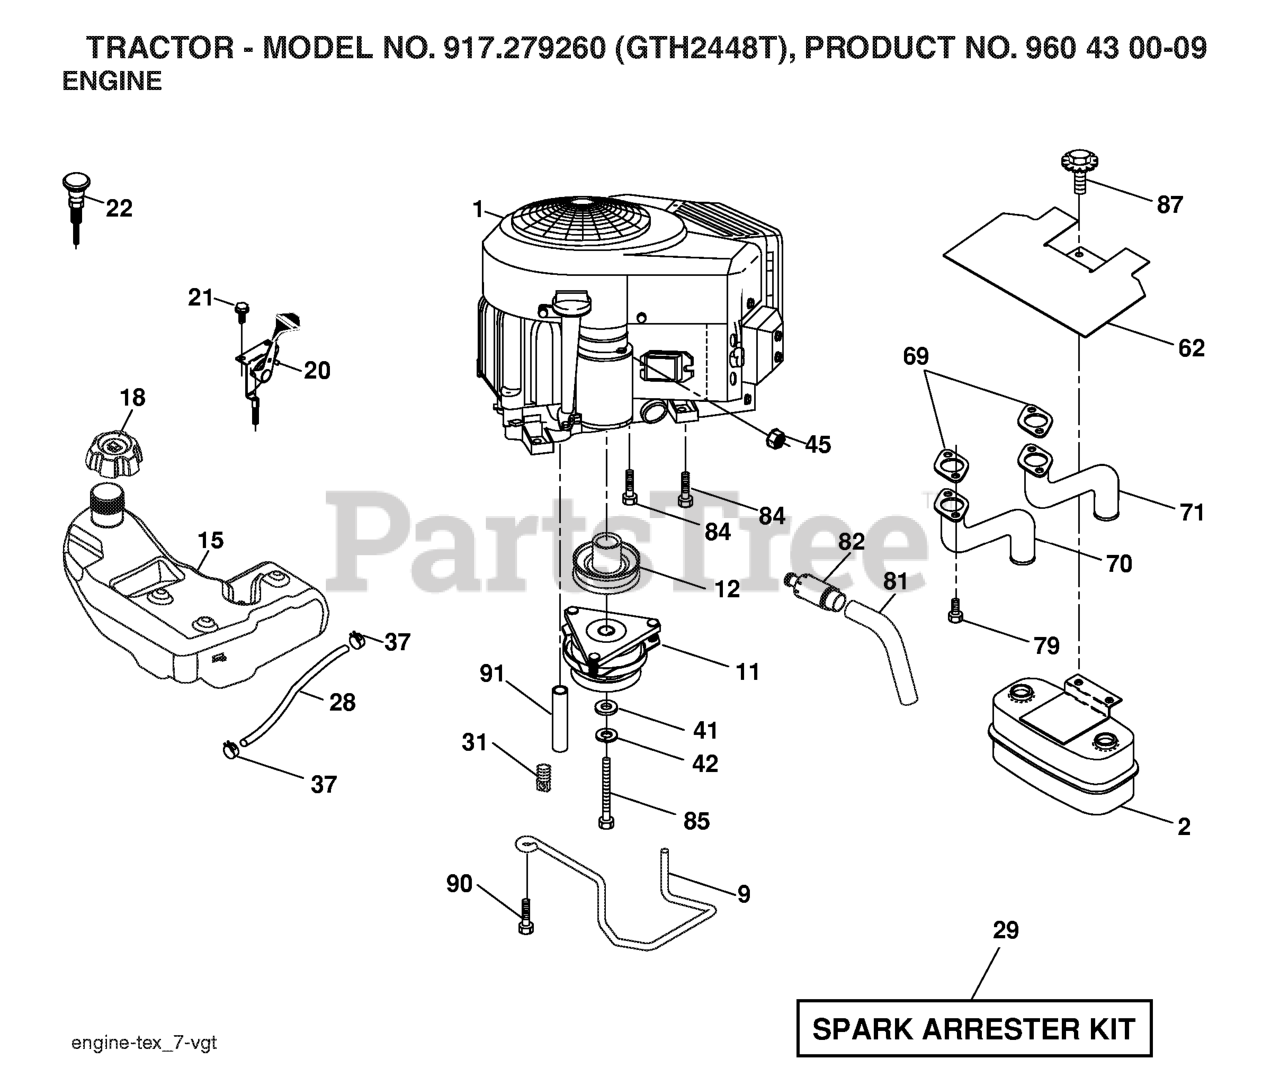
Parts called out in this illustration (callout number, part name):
2	MUFFLER.TWIN.CYL.LOW.TONE
9	KEEPER.BELT.ENGINE.3.25 (3 2)
11	CLUTCH MZ ZTR GT.48/54"1.125"
12	PULLEY.ASM.ENGINE.1-1/8X3-1/4
15	TANK.FUEL.4GAL
18	CAP.FUEL.TANK.3"GREY
20	THROTTLE CABLE
21	SCREW
22	CONTROL.CHOKE.ERGO.PUSH-IN.BLA
28	LINE.FUEL.64"REAR.EMIS
29	KIT.SPARK ARRESTOR 794945 B&S
37	HOSE CLAMP
42	LOCKWASHER
45	NUT
62	RP SHIELD HEAT MUFFLER
69	GASKET.MUFFLER
70	RP.EXHAUST.TUBE.LH.BS/TWIN
71	EXHAUST.TUBE.RH.BS/TWIN
79	SCREW.SOCKET.HEAD.5/16-18
81	TUBE, DRAIN OIL ASM.
82	PLUG DRAIN OIL EASY
84	SCREW.3/8-16
85	BOLT HEX 7/16-20 X 3.75 GR. 5
87	BOLT.5/16-18UNCX1.W/SEMS.BLK
90	SCREW 3/8-16X1
91	BUSHING.1.375OD
